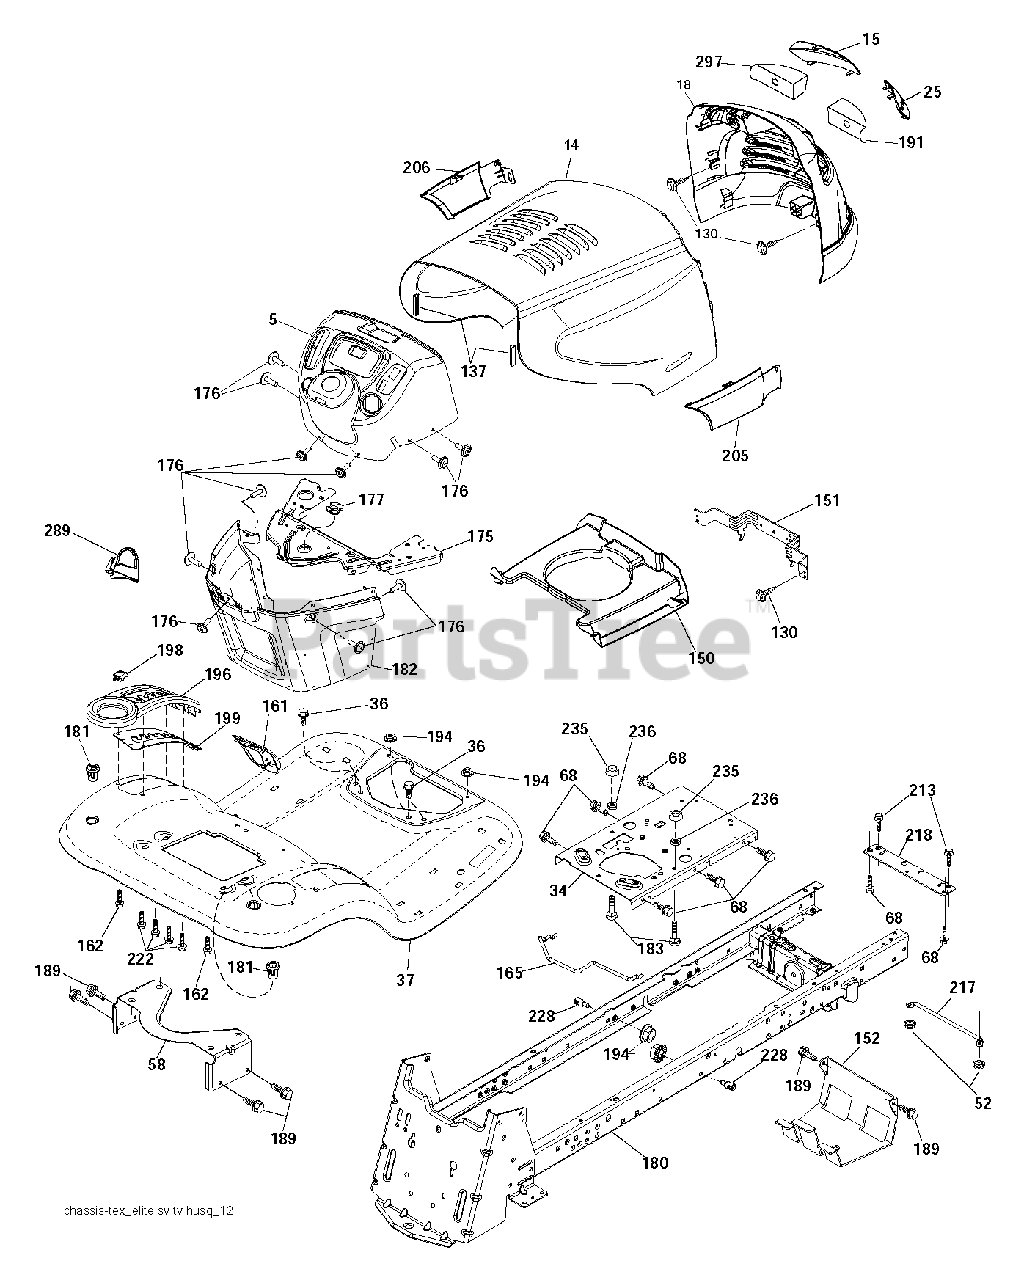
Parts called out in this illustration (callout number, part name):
14	HOOD.PNT.ELITE.TVENT.SVENT.SSK
18	GRILLE.ELITE HUSQ.BLACK.DL.
34	PLATE.ENGINE.WELDED.CHASSIS
36	SCREW 5/16"
52	LOCKNUT
58	BRKT.SUPPORT.FNDR/TANK
68	SCREW LT
130	SCREW.#10 X 0.750.BOS (2 2)
137	BUMPER.HOOD.LARGE.1.75"
150	AIR DUCT
151	BRACKET PIVOT
152	SHIELD.BROWNING.W/TEX
161	CONSOLE.FUEL.WINDOW.STGT.BLACK
162	SCREW.HI-LO.CONSOLE
165	SUPPORT.TANK.REAR.W/TEX
175	CROSSMEMBER.LT
176	SCREW.#10-24X5/8.RN.QU
177	BUSHING,STEERING
180	CHASSIS.GT.SLOPED.DRAWBAR.
181	FEND/FTRST.PCH.CPH.NFW
182	DASH.LOWER.LT.CCS
183	BOLT.5/16-18X1-1/4 FULL THD
189	SCREW
191	INSERT.REFLECTIVE.RH.
194	NUT LOCK HEX FLANGE 5/16-18
198	INDICATOR.DECK.LIFT.RED
199	PLATE DECK LIFT
205	SKIRT.SIDE.RH.ELITE.HUSQ.428
206	SKIRT.SIDE.LH.ELITE.HUSQ.BLACK
213	BOLT
217	ROD.PIVOT.HOOD
218	X-PIECE.HOOD.STOP.NON/
222	SCREW.1/4-20X5/8
228	STUD.FASTNER.W/ANTI-ROTATE
235	SPACER FENDER
236	NUT.CENTERLOCK.5/16-
289	PLUG CRUISE HOOK PHONE
297	INSERT LENS
